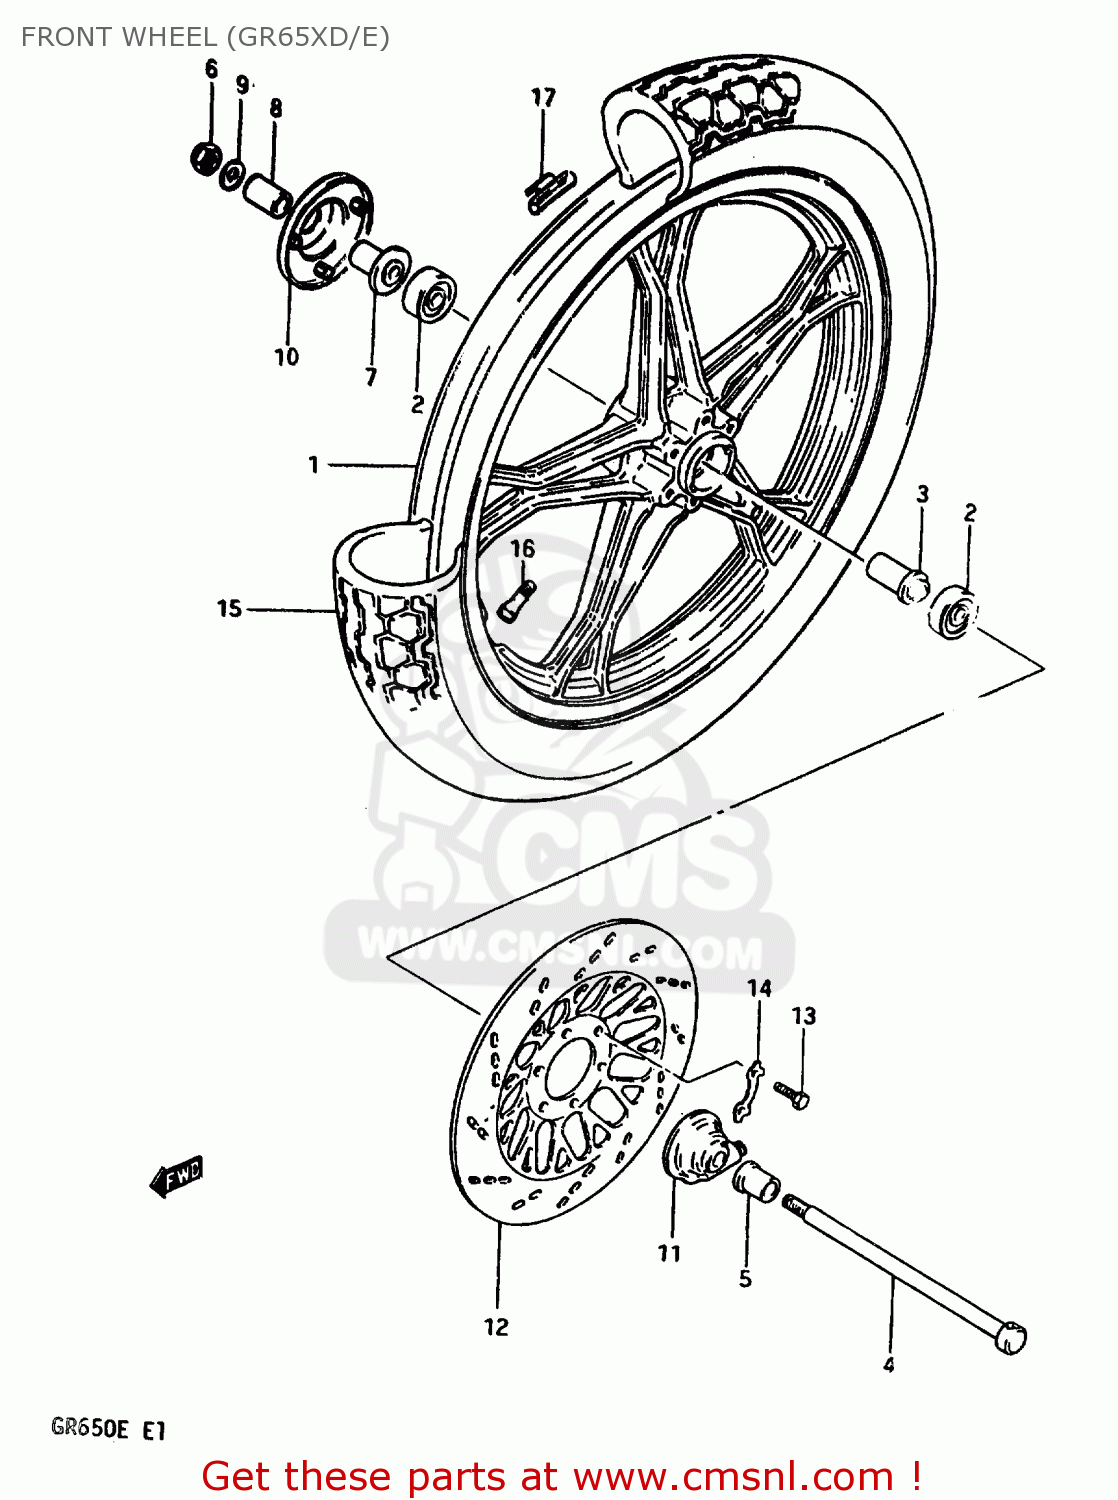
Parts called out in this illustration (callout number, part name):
1	CASTING WHEEL,FRONT 1.85
2	BEARING
3	SPACER,FR HUB BEARING
4	AXLE,FR
5	SPACER,FRONT AXLE,RIGHT
6	NUT
7	SPACER,FR AXLE,R
8	SPACER,FRONT AXLE,RIGHT
9	WASHER
10	COVER,FR HUB,R
11	BOX ASSY,SPEEDOMETER GEAR
12	DISC,FR BRAKE,L
13	BOLT(8X25)
14	WASHER
15	TIRE,FRONT
16	VALVE,TIRE
17	BALANCER,WHEEL
